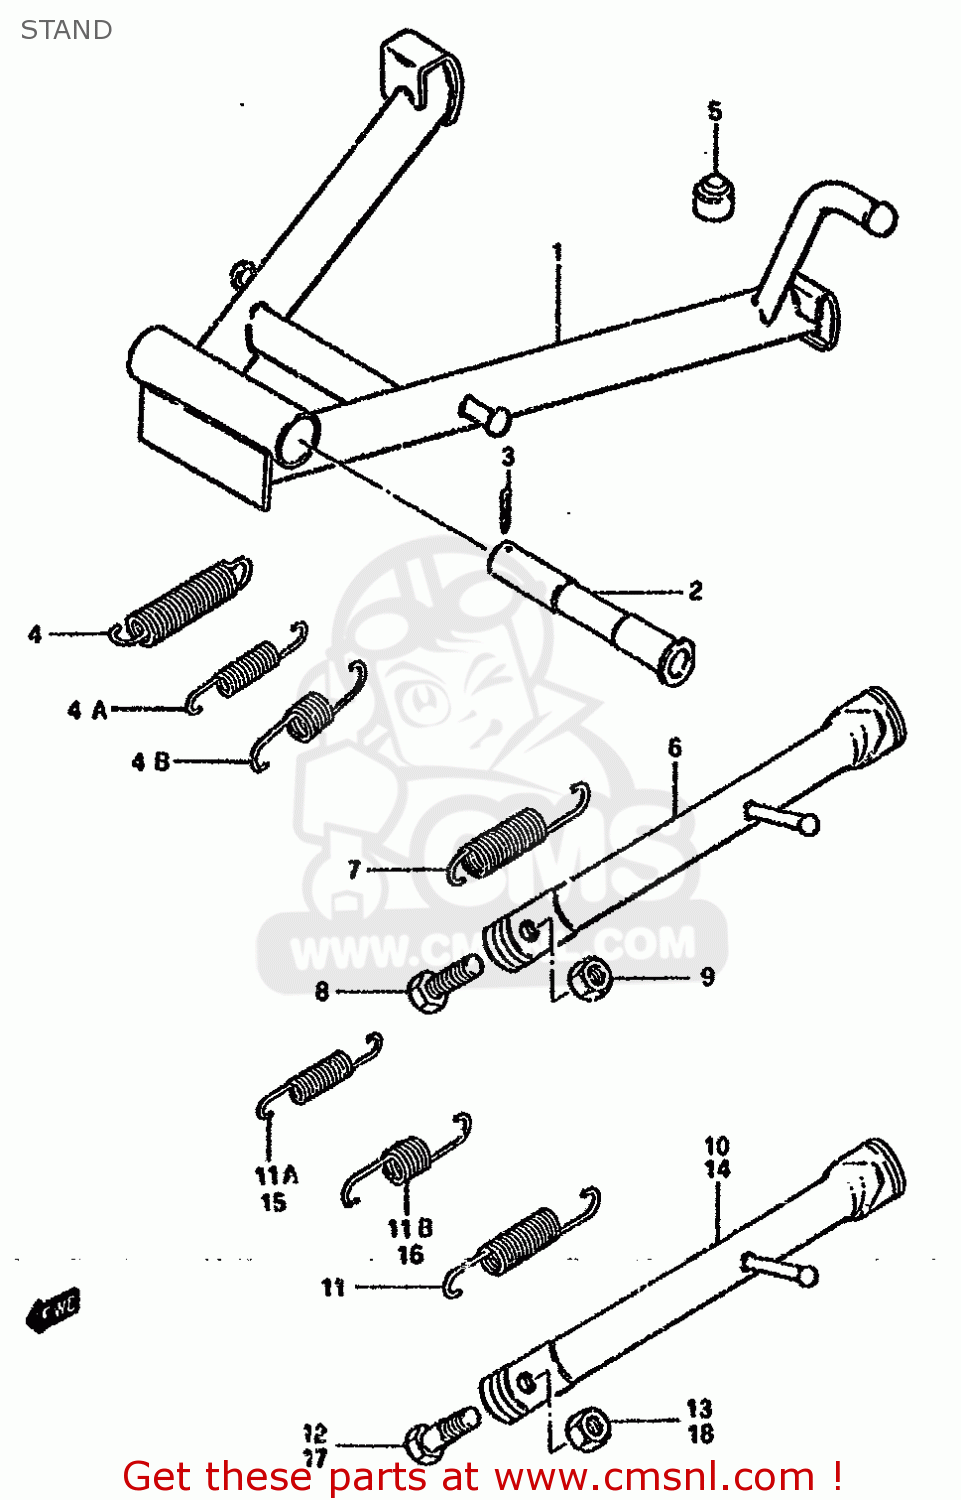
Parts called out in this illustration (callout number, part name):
1	STAND,CTR
2	SHAFT,CENTER STAND
3	COTTER PIN
4	SPRING
4A	SPRING
4B	SPRING
5	CUSHION
6	STAND,PROP
7	SPRING
8	BOLT(10X30)
9	NUT
10	STAND,PROP
11	SPRING
11A	SPRING
11B	SPRING
12	BOLT L:30
13	NUT
14	STAND,PROP
15	SPRING
16	SPRING
17	BOLT(10X30)
18	NUT
